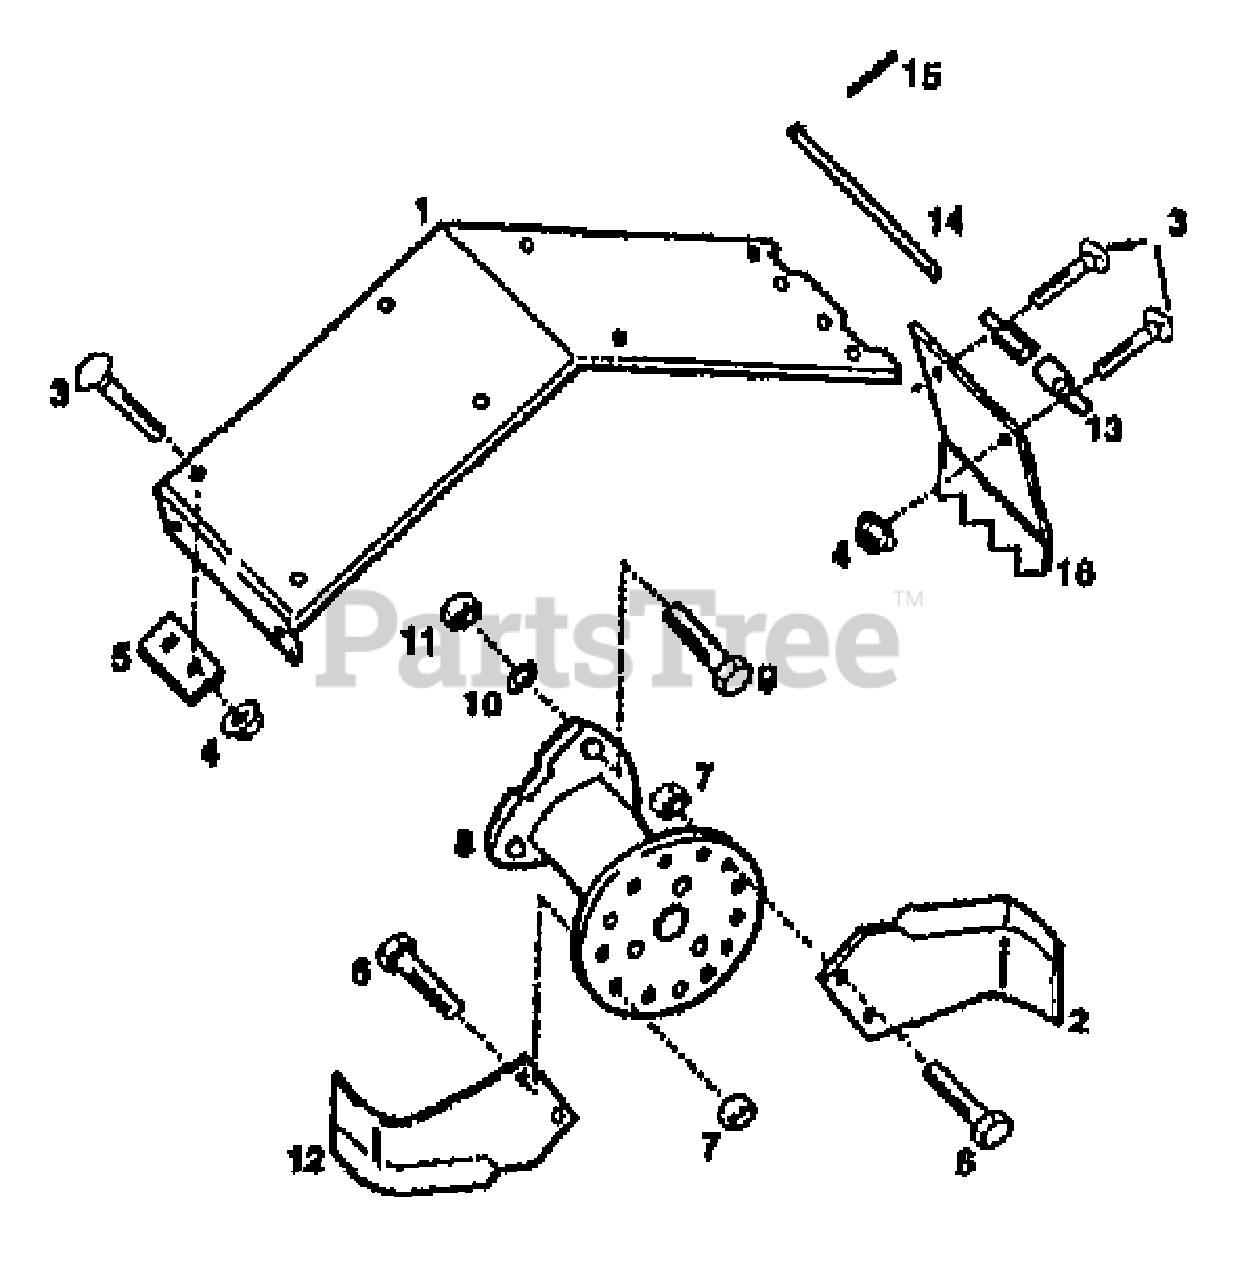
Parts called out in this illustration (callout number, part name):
1	EXTENSION-HOOD
3	SCR-CARR 5/16-18X.75 G2 ZP
4	NUT-HFLK 5/16-18 ZP
5	CONNECTOR-HOOD
6	SCR-HH 3/8-16X1.25
7	NUT-H/LK 3/8-16
8	SPACER-TINE
9	SCR-HH 1/2-13X1.75 G5 ZP
10	WASHER-LK .5
11	NUT-HEX JAM 1/2-13
13	HINGE-TINE HOOD
14	PIN-TINE HINGE
15	PIN-COTTER .09X.75 ZP
16	LEVELLING BOARD EXTENSION
